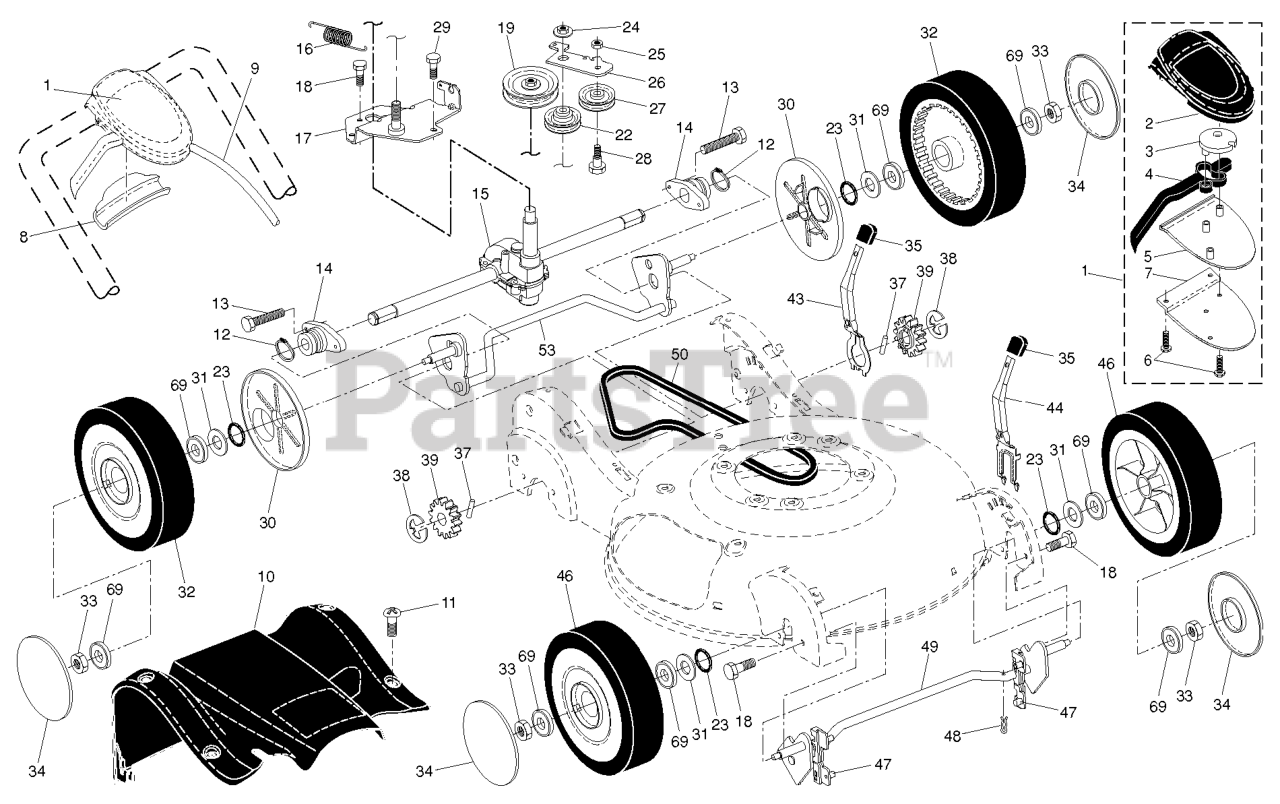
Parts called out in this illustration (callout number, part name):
1	CONTROL.DR.HV.RWGD.GRY/BLU
2	COVER TOP AUTO WALK CONTROL
3	PULLEY.CAM.DRIVE.CONTROL.HV
4	LEVER
5	COVER BOTTOM AUTO WLK CONTROL
6	SCREW, PHILLIPS HEAD 10 X 5/8
7	BRACKET.DRIVE.CONTROL.MOUNT.BL
8	EZ WALK SNAP COVER PLATE
9	ASM.CABLE.
10	COVER.DRIVE.REAR.21.HV.GRAY
12	RETAINING RING (2 2)(3 2)
13	SCREW.1/4-20X21/4.HEX.
14	BEARING / AXLE SUPPORT
15	TRANSMISSION.21.RWGD.HV
17	BRACKET, GEAR CASE / DRIVE
19	RP PULLEY.DRIVE.EZ
22	PULLEY.IDLER.V-BELT
23	O-RING..070X.487.NEOPRENE
24	NUT.HEX.FLANGE.3/8-16.LOCKNUT
25	NUT.CENTERLOCK.5/16-
26	ARM.IDLER.BZP
27	IDLER PULLEY
28	SHOULDER BOLT
29	SCREW 14-20 X 5/8
30	DUST COVER, WHEEL
31	WASHER.FLAT.1/2
32	WHEEL.9X2.25.LP.TIGER.BLACK
33	NUT.HEX.FLANGE.3/8-16.LO(3 2)
34	HUBCAP.WHEEL.5.SPOKE.SILVER
35	KNOB.SELECTOR.SPRG.H-GRY (2 2)
37	PAWL, DRIVE
38	E-RING 7/16 RE
39	PINION.14.TEETH.FGD
43	LEVER, SELECTOR, HEIGHT, REAR
44	LEVER, SELECTOR, HEIGHT, FRONT
46	WHEEL.9X2.25.LP.TIGER.BLK
47	BUSHING.FRONT.TORQUE.SHAFT
48	SPRING RETAINER
49	SHAFT FRONT
50	BELT, DRIVE
53	SHAFT.ASM.REAR.TORQUE.HV.BZP
69	BEARING.8".WHEEL
